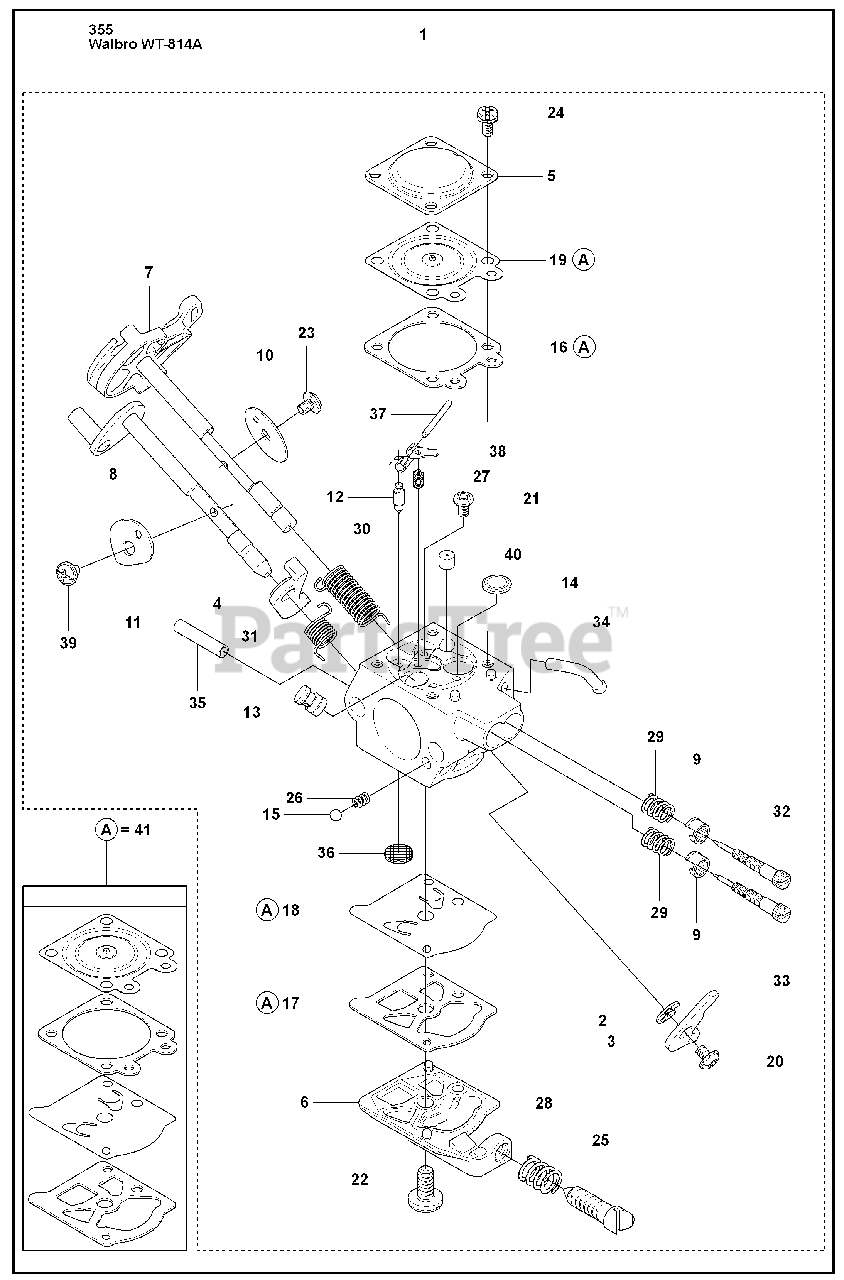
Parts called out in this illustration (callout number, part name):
1	CARBURETOR WT-814A
2	E CLIP
5	DIAPHRAGM COVER
9	LIMITER CAP
12	INLET NEEDLE
14	PLUG
18	DIAPHRAGM, FUEL PUMP
19	METERING DIAPHRAGM
23	SCREW
24	RP SCREW W/ WASHER
28	SPRING
32	NEEDLE
33	NEEDLE
36	FUEL INLET SCREEN
37	FULCRUM PIN
41	GASKET SET
